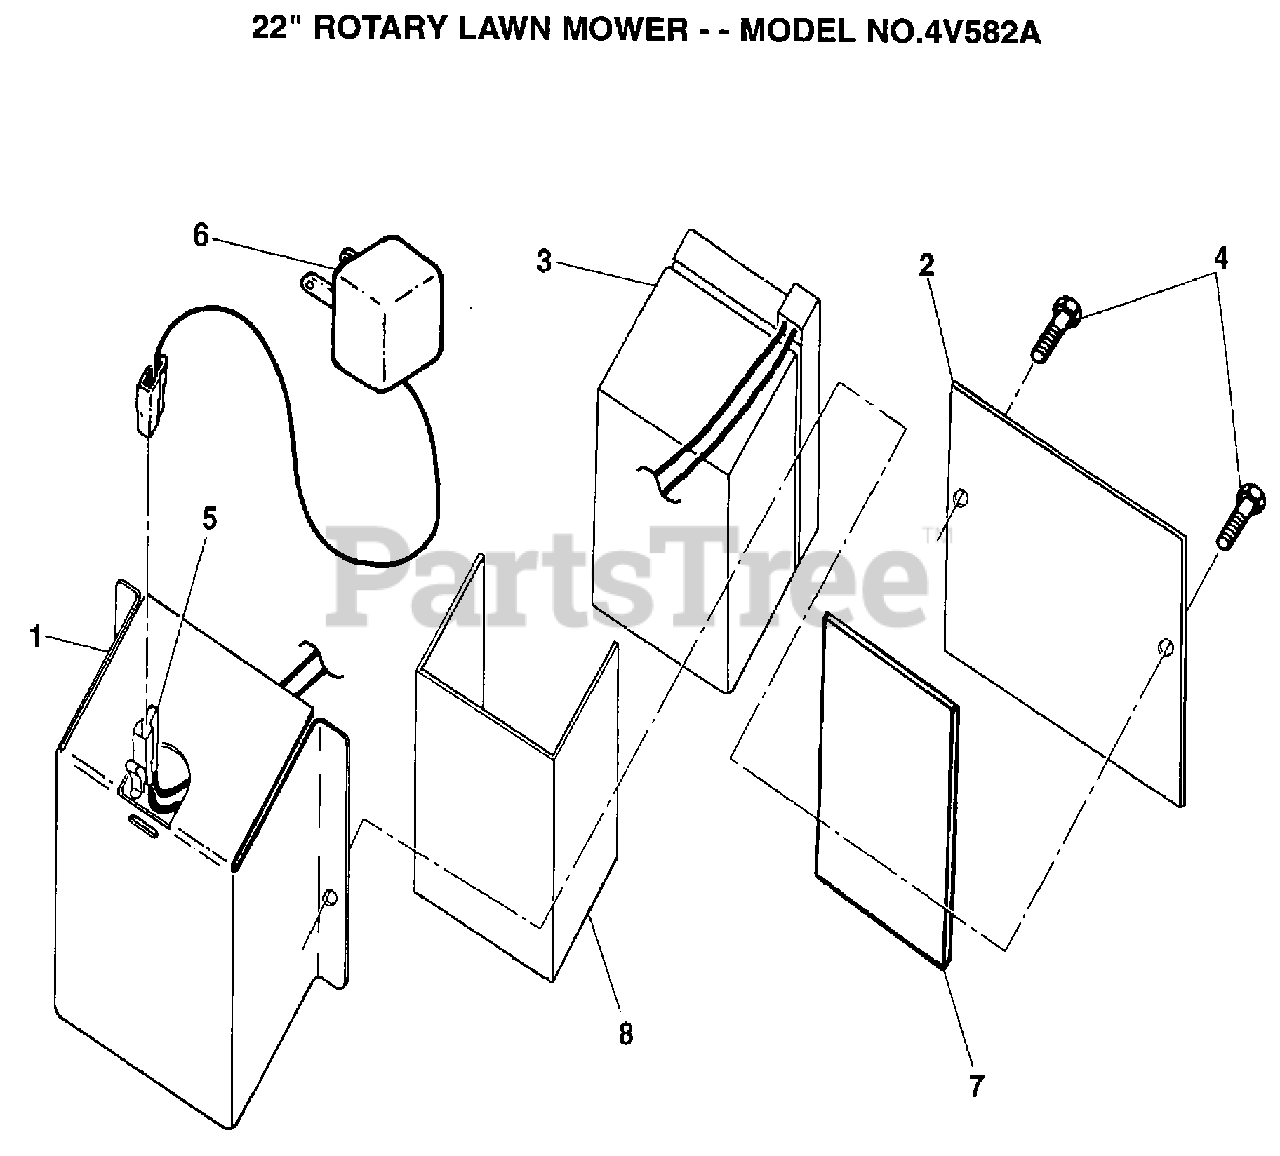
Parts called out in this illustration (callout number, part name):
4	TAPPING SCREW
5	CONNECTOR PM
6	CHARGER PM
7	"PAD PM, BATTERY"
8	"WRAP, BATTERY"
